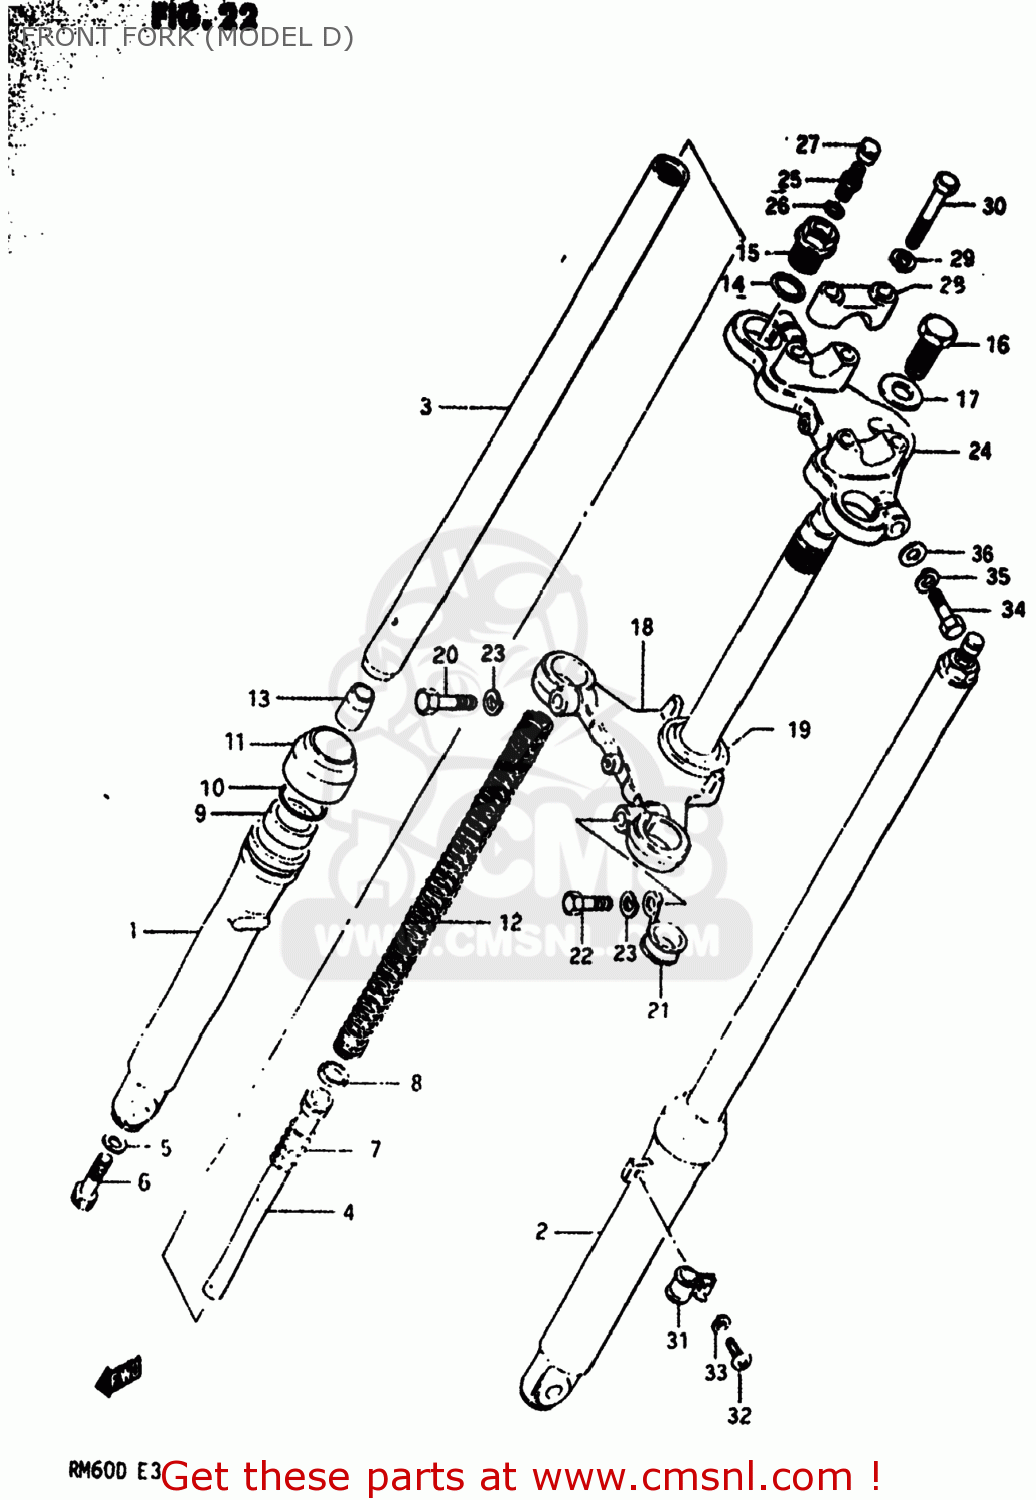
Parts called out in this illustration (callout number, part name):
1	TUBE,OUTER,RIGHT
2	TUBE,OUTER,LEFT
3	TUBE,FORK,INNER
4	CYLINDER,FRONT FORK
5	GASKET (NAS)
6	BOLT(8X27)
7	SPRING,REBOUND
8	RING,PISTON
9	OIL SEAL,FRONT FORK
10	CIRCLIP,FORK OIL SEAL
11	DUST SEAL
12	SPRING
13	PIECE,OIL LOCK
14	O RING
15	CAP,FORK
16	BOLT
17	WASHER,STEERING STEM
18	STEM,STEERING
19	RACE,STEERING OUTER LWR
20	BOLT 10X30
21	CLIP,CABLE
22	BOLT,M10X1.25X
23	LOCK WASHER
24	HEAD,STEERING STEM
25	VALVE,AIR
26	O-RING
27	CAP,VALVE AIR
28	HOLDER,HANDLE UPR
29	LOCK WASHER
30	BOLT
31	CLIP,CABLE
32	SCREW
33	LOCK WASHER
34	BOLT 8X40
35	LOCK WASHER
36	WASHER
